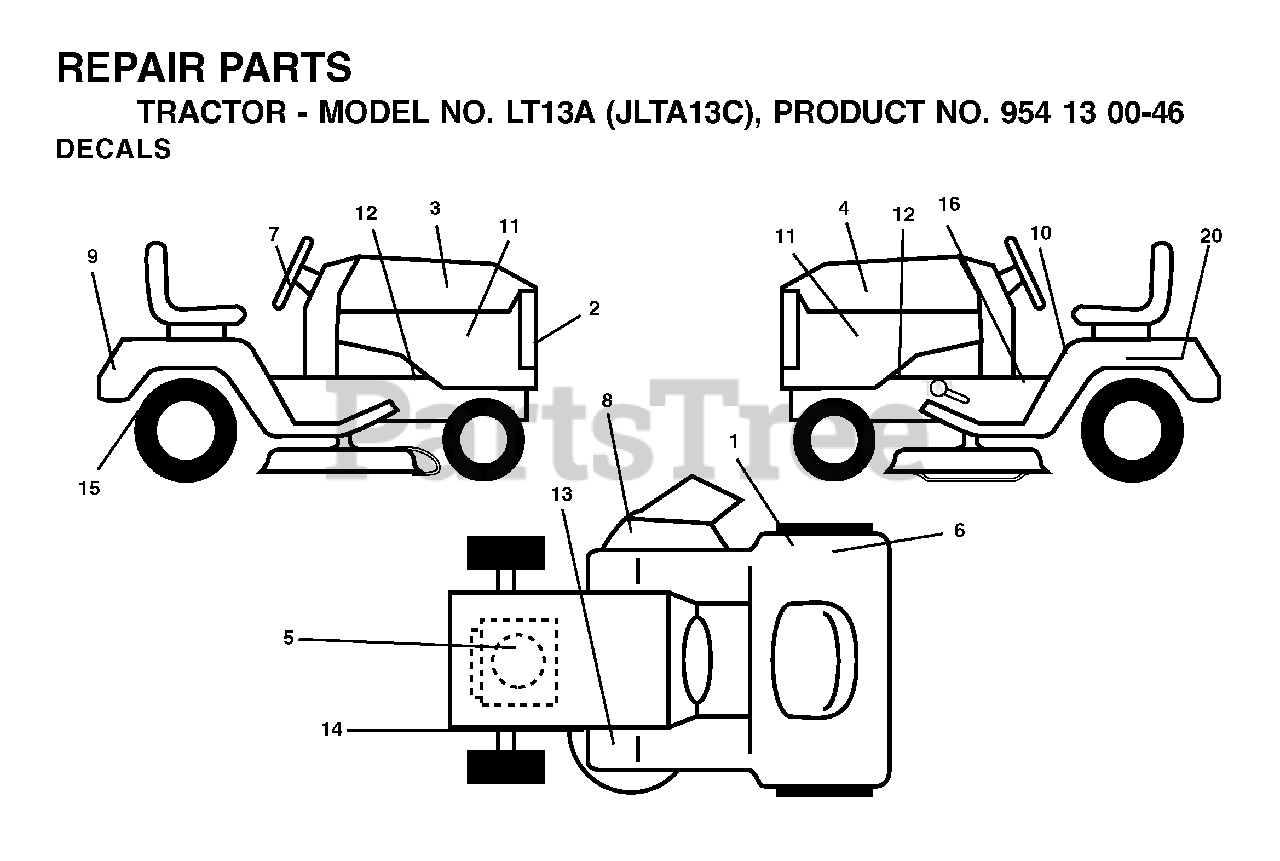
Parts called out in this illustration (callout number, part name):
1	DECAL CERTIFICATION
5	DECAL HP ENGINE
6	DECAL EUROPE STANDARD CE
8	DECAL MOWER CUT/FINGER
10	DECAL READ OWNER'S MAN SYMS
14	DECAL V-BELT SCHEMATIC
16	DECAL PARK BRAKE
20	DECAL BTRY SYMBOLS
